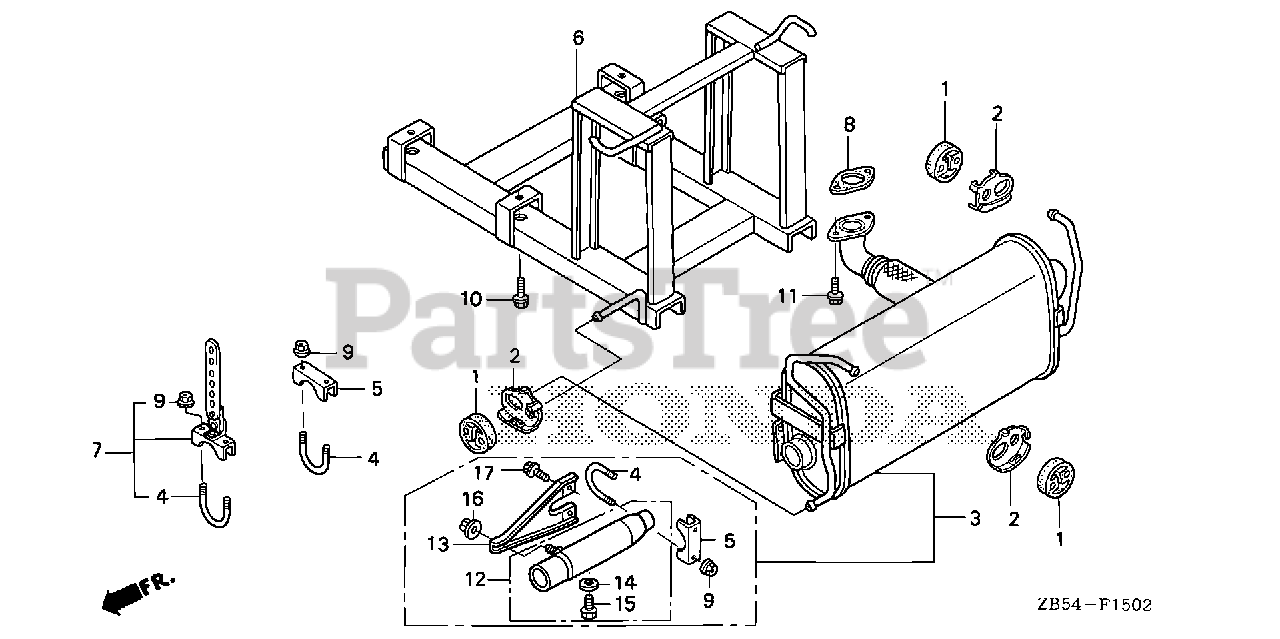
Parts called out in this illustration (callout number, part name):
1	RUBBER, EX. PIPE MOUNTING (60X50X20)
2	BRACKET, MOUNTING
4	BOLT, MUFFLER TAIL PIPE
5	CLAMP, MUFFLER TAIL PIPE
6	STAY, MUFFLER *NH105* (MAT BLACK)
7	BRACKET ASSY., MUFFLER TAIL PIPE
8	GASKET, MUFFLER
9	NUT, FLANGE (8MM)
10	BOLT, FLANGE (8X16) Use from Engine SN 1000016.
11	BOLT, FLANGE (8X20) Use up to Engine SN 1609606.
12	ARRESTER, SPARK
13	BRACKET A, MUFFLER
14	WASHER, PLAIN (10MM)
15	BOLT, HEX. (10X12)
16	NUT, HEX. (10MM)
17	BOLT, FLANGE (6X12) Use up to Engine SN 1543277.
